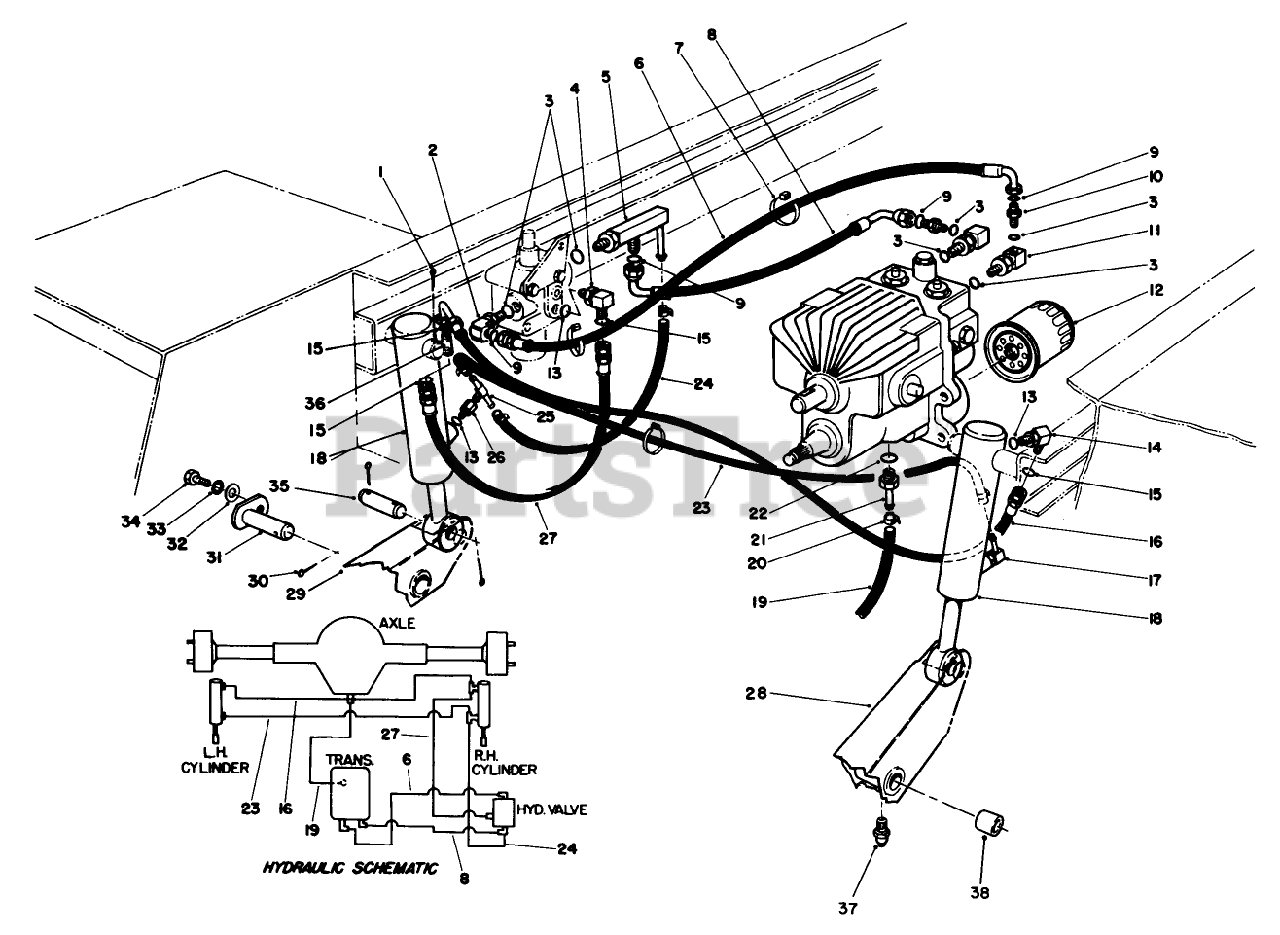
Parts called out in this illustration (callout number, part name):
1	PIN-COTTER
2	FITTING-ELBOW, 90 DEG
3	O-RING
4	FITTING-90 DEG
5	FITTING ASM
6	HOSE ASSEMBLY
7	TIE-CABLE
8	HYDRAULIC HOSE ASM
9	O-RING
10	FITTING-STRAIGHT
11	FITTING-HYD, 90 DEG
12	FILTER-OIL, TRANSMISSION
13	O-RING
14	90 DEGREE ELBOW
15	O RING
16	HOSE ASSEMBLY
17	STEM-HOSE
18	Cylinder-Hydraulic
19	HYDRAULIC HOSE
20	CLAMP-HOSE
21	Fitting (Incl. Ref. #21)
22	O-RING
23	HOSE-FUEL
24	HYDRAULIC HOSE
25	MALE TEE FITTING
26	CONN FITTING
27	HOSE ASSEMBLY
28	LH LIFT ARM ASM
29	RH LIFT ARM ASM
30	PIN-COTTER
31	Pin-Pivot
32	WASHER-FLAT
33	WASHER-LOCK
34	SCREW-HH
35	PIN-CYLINDER
36	FITTING-TEE
37	FITTING-GREASE
38	7/8 ID X 1.128 X 7/8 LG BSHG
